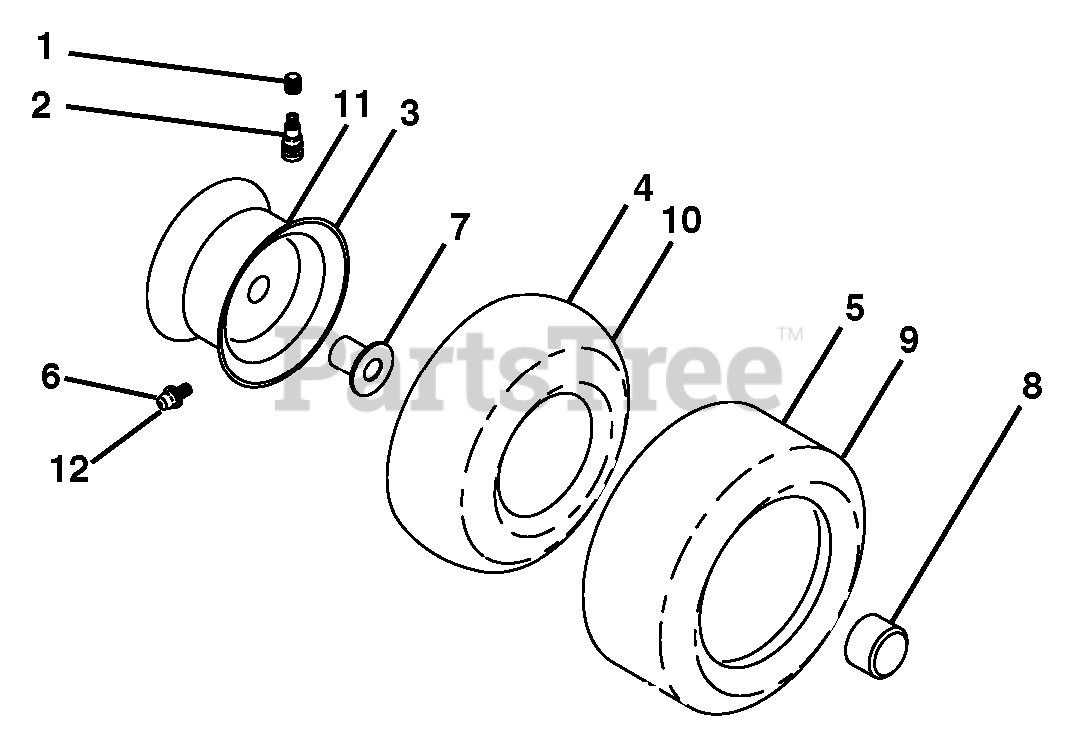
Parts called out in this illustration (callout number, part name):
2	VALVE STEM LT
3	RIM ASSEMBLY, FRONT
4	TUBE.16X6.5/7.5-8
5	TIRE HEAVY DUTY
6	FITTING LT
7	BEARING T
8	CAP, AXLE BLK
9	TIRE HEAVY DUTY
10	TUBE.23X9.5-12
11	RIM.ASM.12X7.REAR.SILVER
12	ZERK FITTING M
